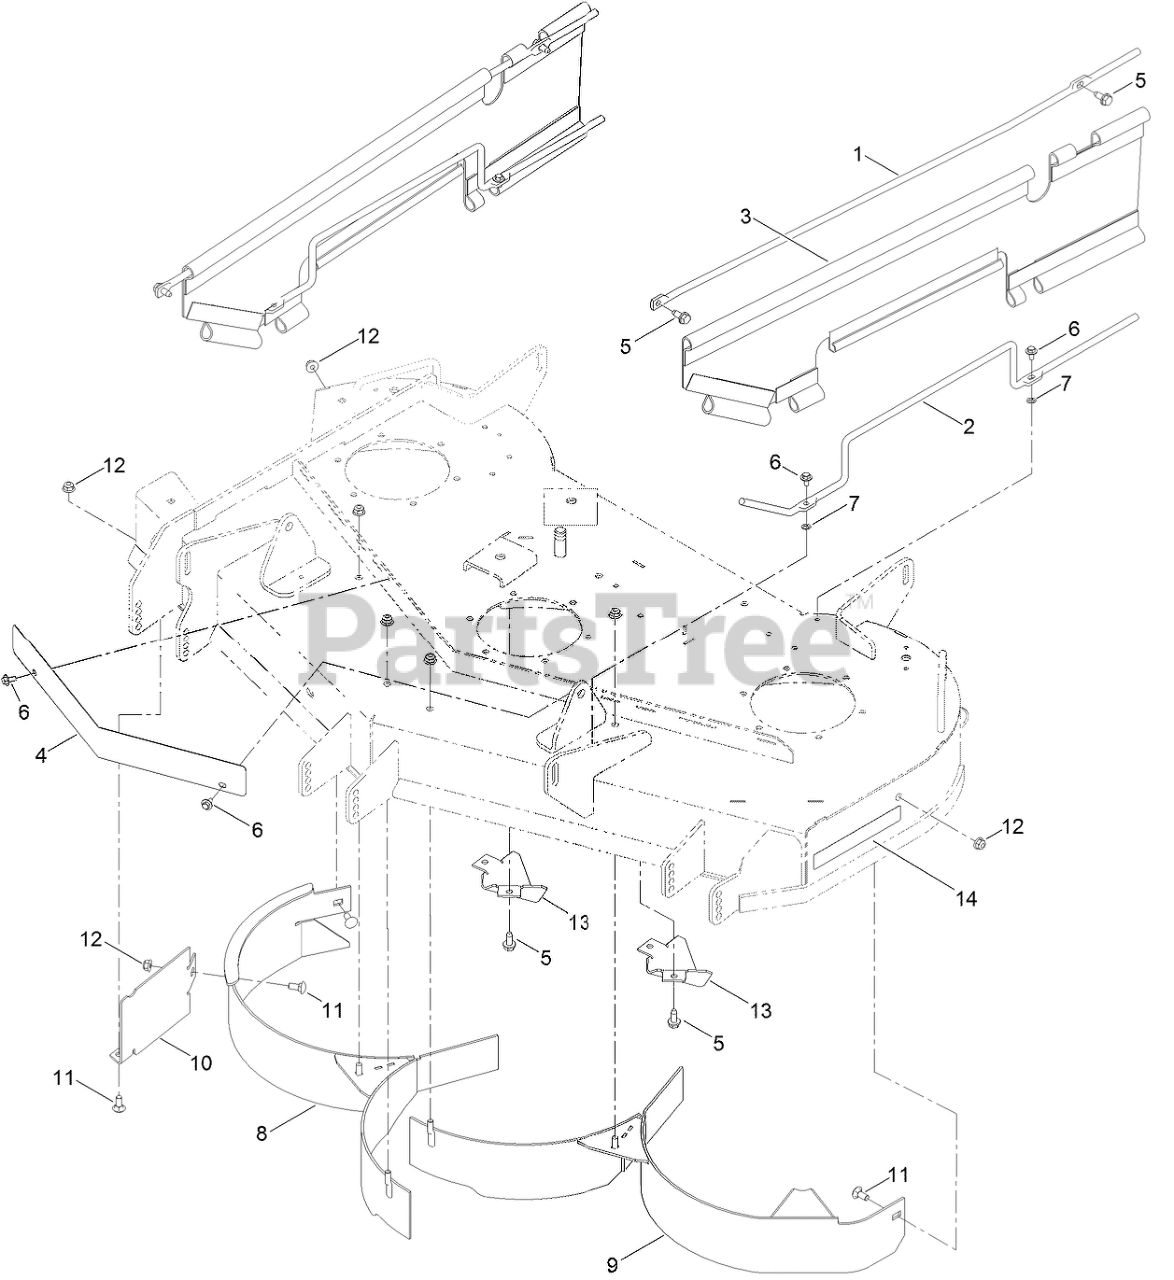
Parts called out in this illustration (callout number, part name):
1	ROD SUPPORT, UPPER
2	ROD SUPPORT, LOWER
3	GUARD-SIDE
4	SHIELD-FRONT
5	SCREW-HWHTF
6	SCREW-HHFTF
7	NUT-RETAINING
8	RH BAFFLE ASM
9	LH BAFFLE ASM
10	GUARD-BAFFLE
11	BOLT-CARR
12	NUT-HF, NI
13	KICKER-FLANGED
14	DECAL-RECYCLER
